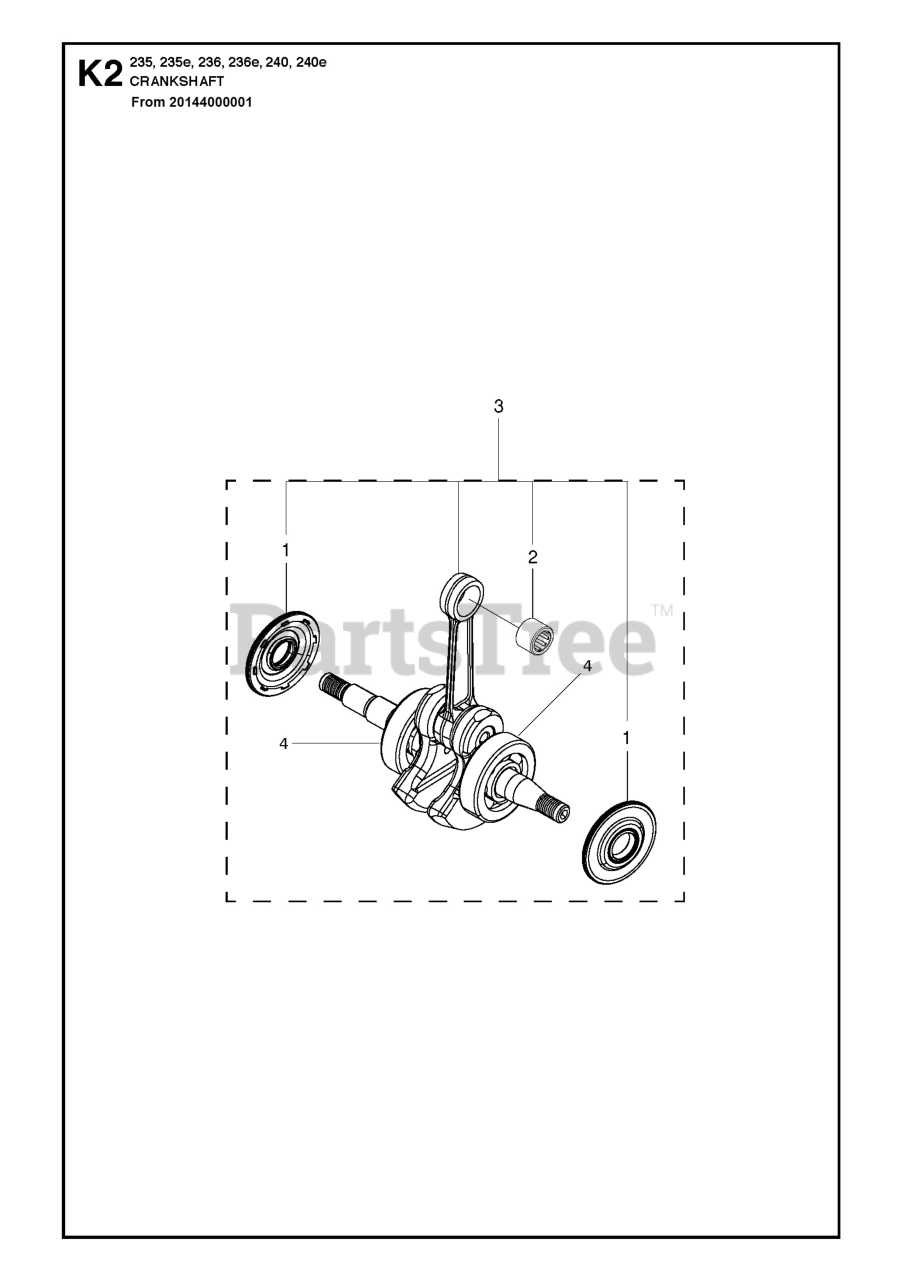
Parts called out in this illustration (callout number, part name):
1	SEAL RADIAL BEARING
2	ASSY CRANKSHAFT
3	Crankshafts
